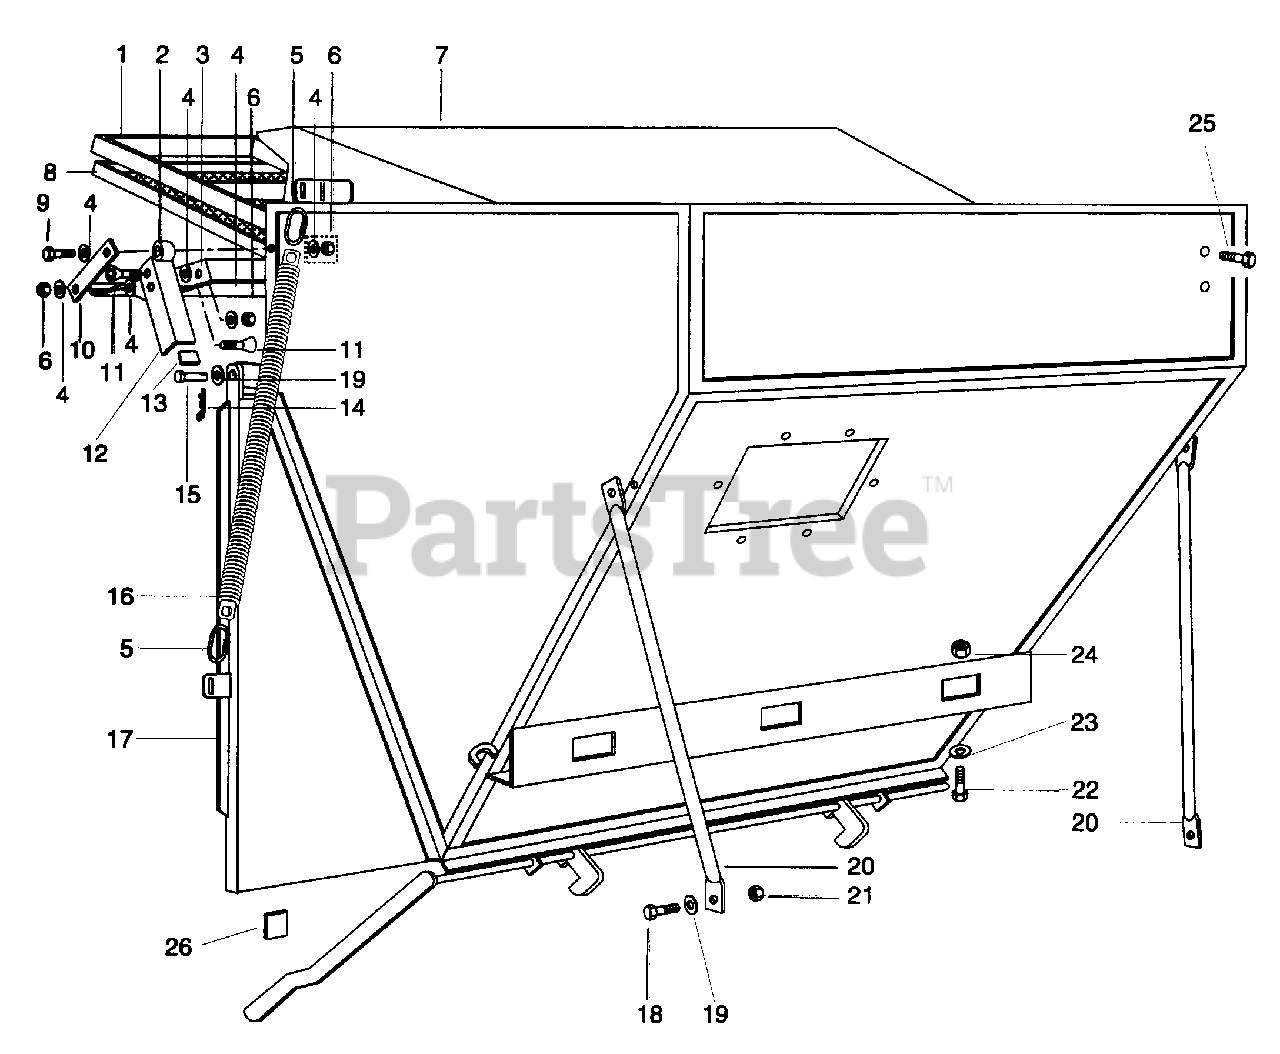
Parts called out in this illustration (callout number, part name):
1	Grid Weldment
2	Screen Door Link Spacer
3	Screen Door Weldment
4	Wshr-Fl-Stl .38 x .875 x .083
5	1/4 Quick Link
6	Nut-Lk-Ctr .31-18
7	Hopper Weldment
8	Single Screen
9	Blt-Hex .31-18 x 1.50 Gr 5
10	Filter Door Linkage
11	Screw-Machine .31-18 x 1.00
12	Filter Door Latch RH
12	Filler Door Latch LH
14	Pin-Cotr .12 x .75
15	Clevis Pin
16	Spring
17	Door Weldment
18	Blt-Hex .38-16 x 1.00 Gr 5
19	Wshr-Fl-Stl .438 x 1.00 x .083
20	Hopper Brace
21	Nut-Lk-Ctr .38-16
22	Blt-Hex .50-13 x 1.25 Gr S
23	Wshr-Fl-Stl .563 x 1.38 x .109
24	Nut-Lk-Ctr .50-13
25	Blt-Hex .32-18 x .50 Gr 5
26	Gasket
